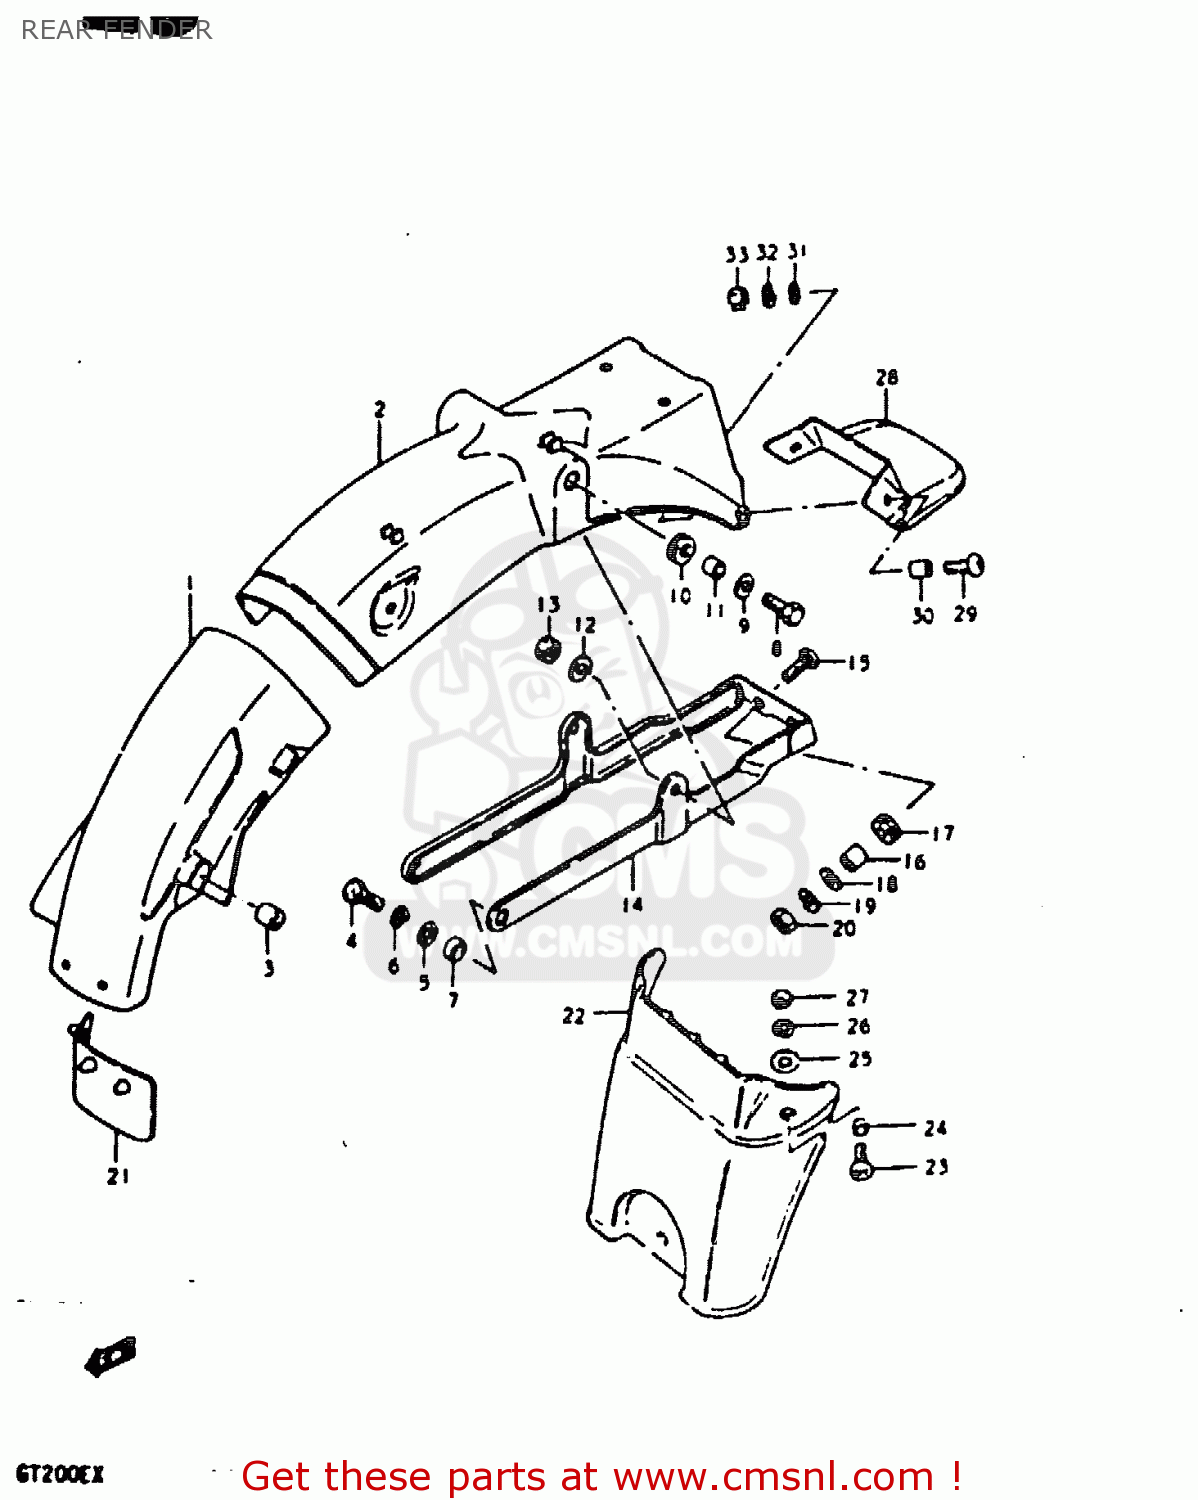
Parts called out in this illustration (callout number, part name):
1	BODY, REAR FENDER FRONT
2	BODY, REAR FENDER REAR
3	CUSHION
4	BOLT
5	WASHER
6	LOCK WASHER
7	SPACER(8.5X12X2.5)
8	BOLT (8X30)
9	WASHER
10	CUSHION
11	SPACER (8.2X12X7.5)
12	LOCK WASHER
13	NUT
14	REINFORCEMENT, REAR FENDER
15	SCREW
16	SPACER (6.1X9X9)
17	CUSHION
18	WASHER(6,5X22X1.6)
19	LOCK WASHER
20	NUT
21	MUD GUARD,REAR FENDER
28	EXTENSION,REAR FENDER
29	SCREW (6X15)
30	SPACER(6.2X8.3X5.7)
31	WASHER(6.5X18X1)
32	LOCK WASHER
33	NUT
